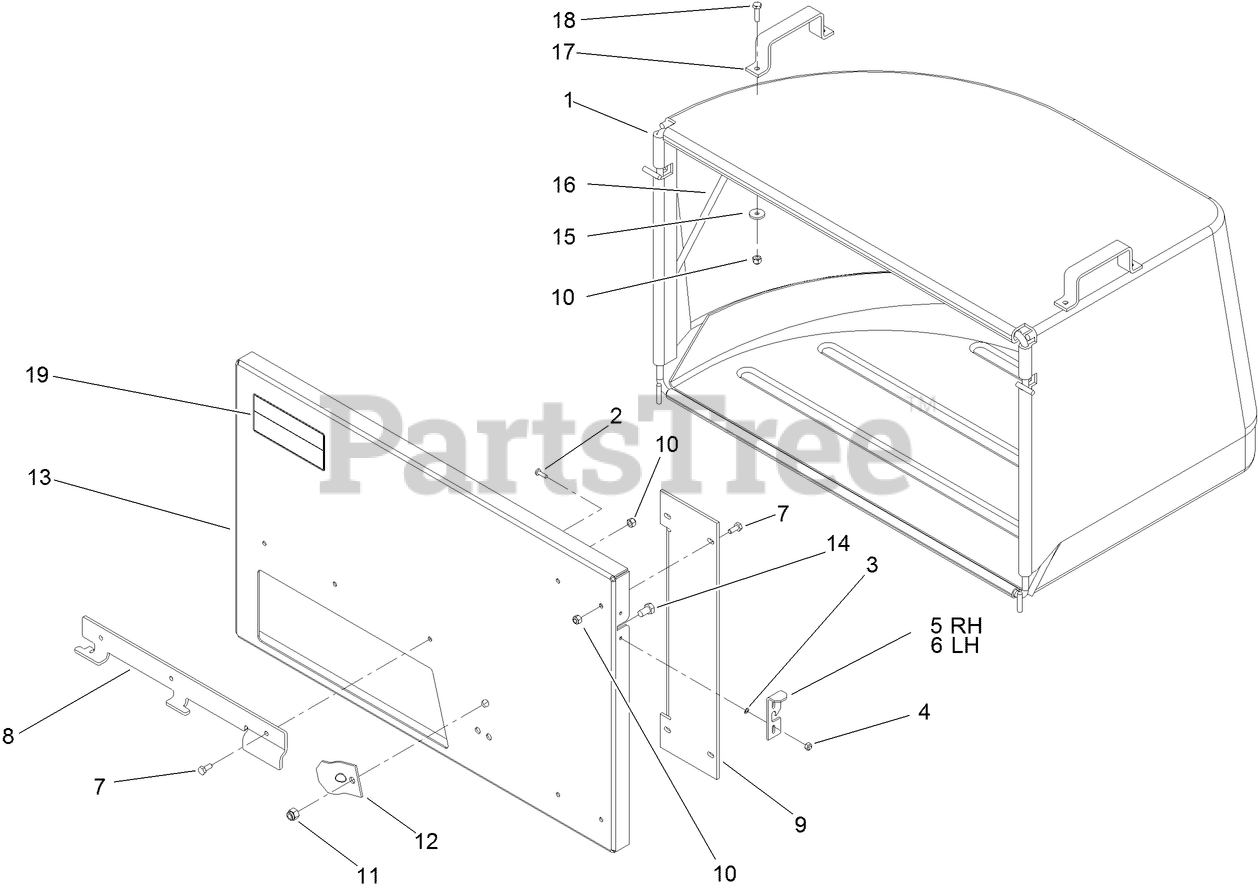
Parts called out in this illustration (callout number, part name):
1	BAG ASM
2	SCREW-PPH
3	WASHER-SPRING
4	NUT-LOCK, NI
5	LATCH-CATCHER, RH
6	LATCH-CATCHER, LH
7	SCREW-HH
8	BRACKET-MOUNTING
9	BRACKET-SUPPORT, BAGGER
10	NUT-LOCK, NI
11	NUT-LOCK, NI
12	Bracket-Clamp
13	PLATE-BAGGER
14	SCREW-HH
15	WASHER
16	FRAME-CATCHER
18	SCREW-HH
19	DECAL-WARNING, BAGGER
